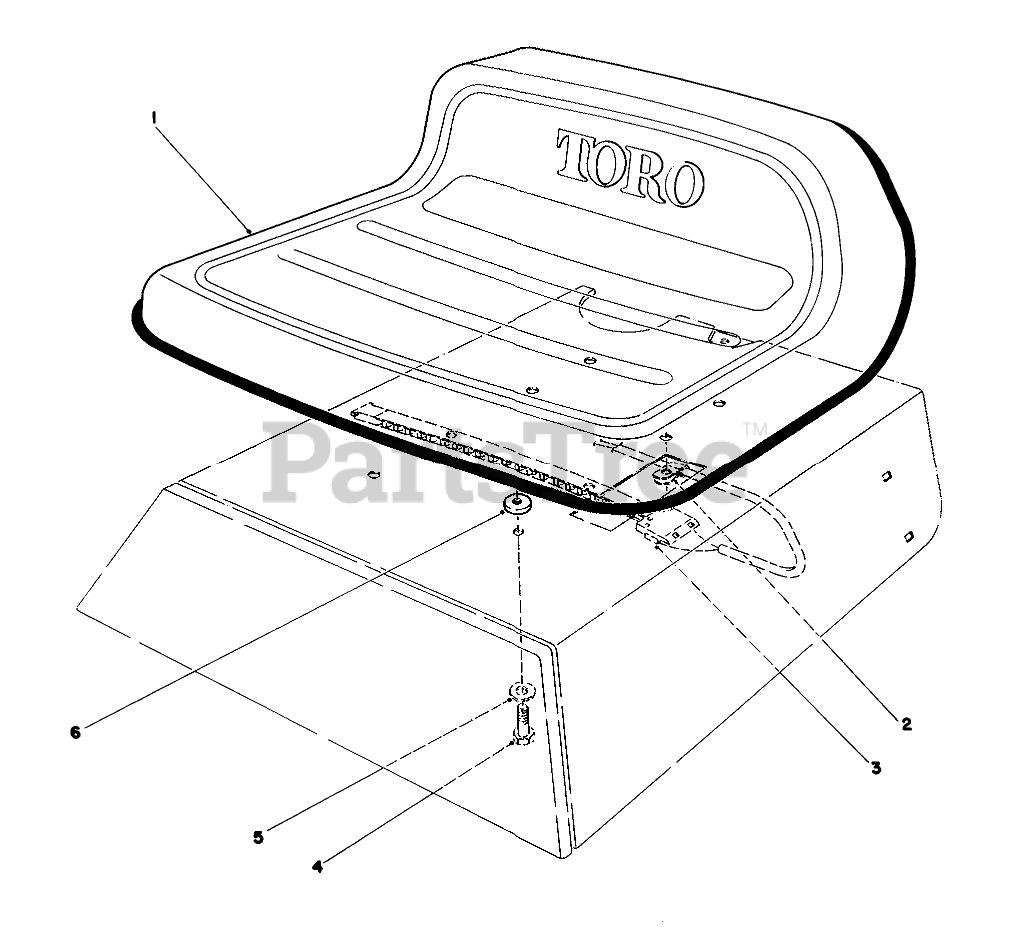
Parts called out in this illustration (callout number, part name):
1	Seat
2	CLIP-FUEL LINE
3	SWITCH-SEAT
4	SCREW-HH
5	WASHER-FLAT
6	SPACER-PIN, MOUNTING
